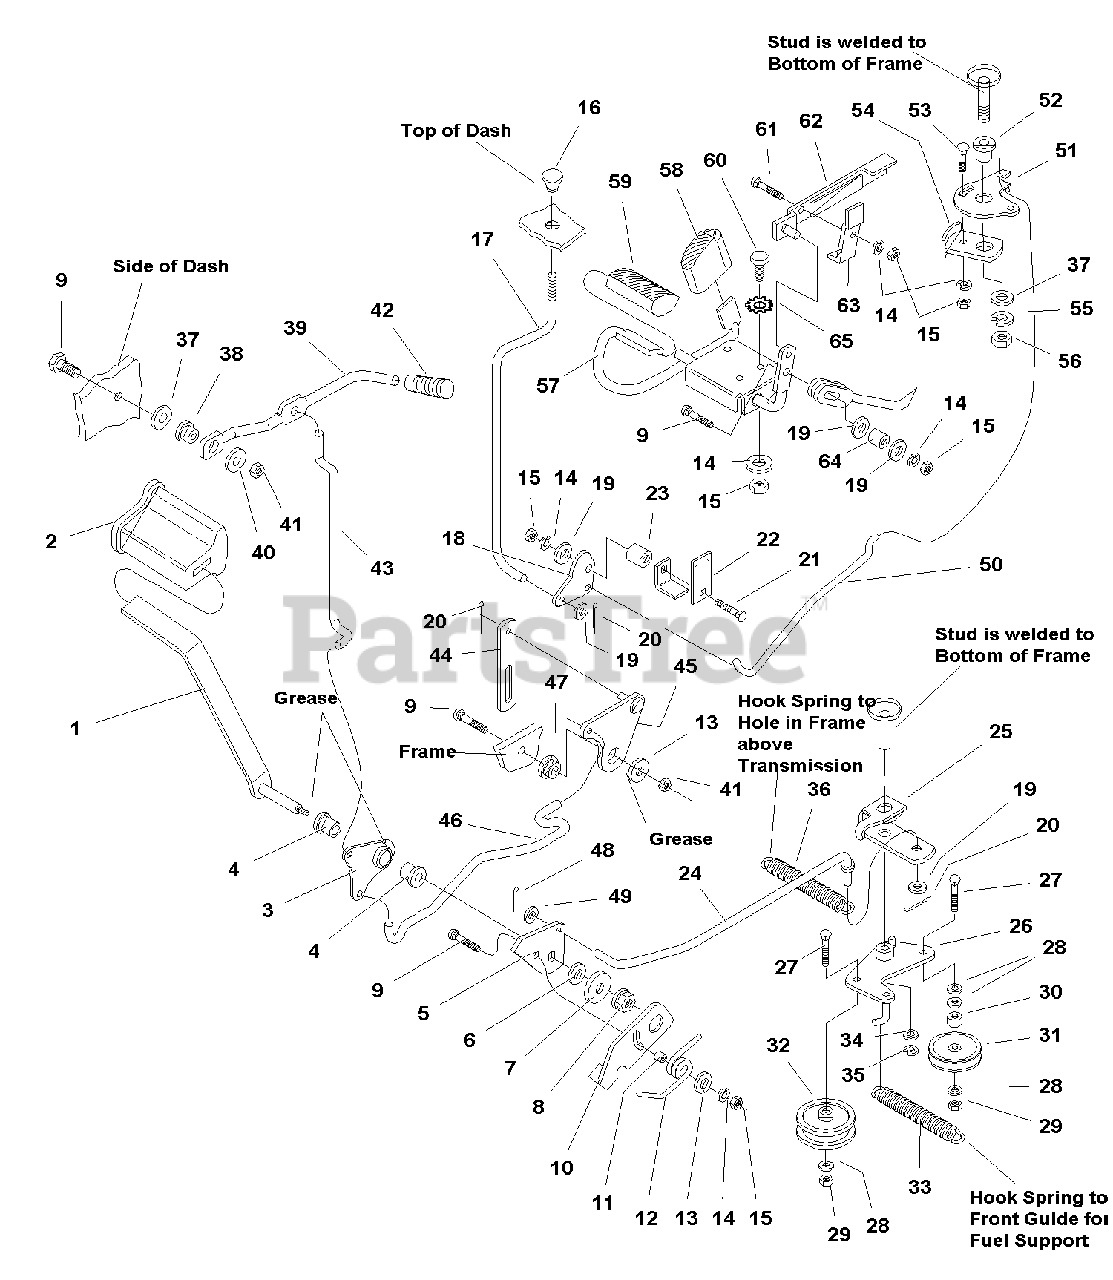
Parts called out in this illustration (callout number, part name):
1	PEDAL & SHAFT ASSEMBLY, Brake
2	FOOT PEDAL PAD
5	ARM, Foot Pedal
6	WASHER, Plain, 3/8
7	WASHER, 3/8
8	NUT, Hex Nylon Lock, 3/8-16
9	CARRIAGE BOLT, 5/16-18 x 1-1/4
10	ACTOATOR, Switch
11	SPACER, 21/64 x 1/2 x 7/16
12	SPRING, Torsion
13	WASHER, 5/16
14	LOCKWASHER, 5/16
15	NUT, Hex, 5/16-18
18	BELLCRANK, Cruise
19	WASHER, 5/16
20	COTTER PIN, 3/32 x 3/4
21	CARRIAGE BOLT, 5/16-18 x 1
22	PLATE, Cruise Lock Light Switch
23	SPACER, 21/64 x 1/2 x 7/32
24	ROD, Clutch
25	PIVOT ASSEMBLY, Clutch / Brake
26	PIVOT ASSEMBLY, Idler
27	CARRIAGE BOLT, 3/8-16 x 1-3/4
28	WASHER, Plain, 13/32
29	NUT, Hex Flange, 3/8-16
30	SPACER, 25/64 x 29/32 x 11/32
32	PULLEY, Idler
33	SPRING, Extension
34	WASHER, 5/8
35	KLIPRING, Extension
36	SPRING, Extension
37	WASHER, 3/8
38	SPACER, 11/32 x 3/4 x 1/2
39	ROD, Lift Handle
40	WASHER, Flat, 5/16
41	NUT, Hex Nylon Lock, 5/16-18
42	KNOB, Rod Lift
43	ROD, Link Lift
44	LINK, Lift, Upper
45	CAM & WELD, PIN ASSEMBLY
46	LINK, Lift Rod
47	SPACER, 11/32 x 1-1/4 x 21/32
48	COTTER PIN
49	WASHER, Plain, 1/4
50	ROD, Cruise
51	BRACKET, Adjustment, Lock Plate
52	SPACER, 25/64 x 15/16 x 21/32
53	CARRIAGE BOLT, 5/16-18 x 7/8
54	LOCK PAD ASSEMBLY
55	LOCKWASHER, 3/8
56	NUT, Hex, 3/8-16
57	PEDAL ASSEMBLY, Foot
58	PAD, Foot Pedal, Reverse
59	PAD, Foot Pedal, Forward
60	CAPSCREW, Hex Head, 5/6-18 x 3/4
61	CARRIAGE BOLT, 5/16-18 x 3/4
62	LOCK PLATE ASSEMBLY
63	BRACKET, Lock Plate ASSEMBLY
64	SPACER, 21/64 x 9/16 x 5/16
65	LOCKWASHER, External Tooth, 5/16
